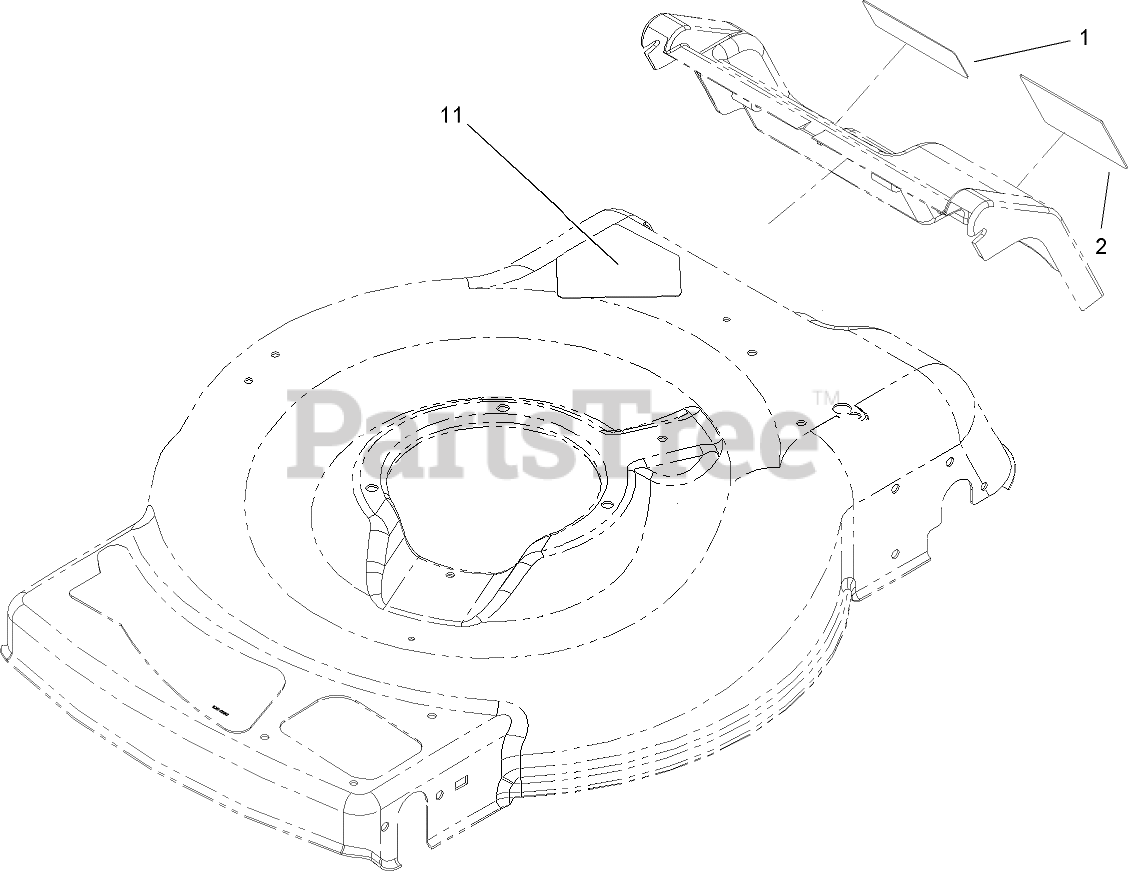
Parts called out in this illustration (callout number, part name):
1	DECAL-WARNING
2	DECAL-WARNING
11	DECAL-DANGER
